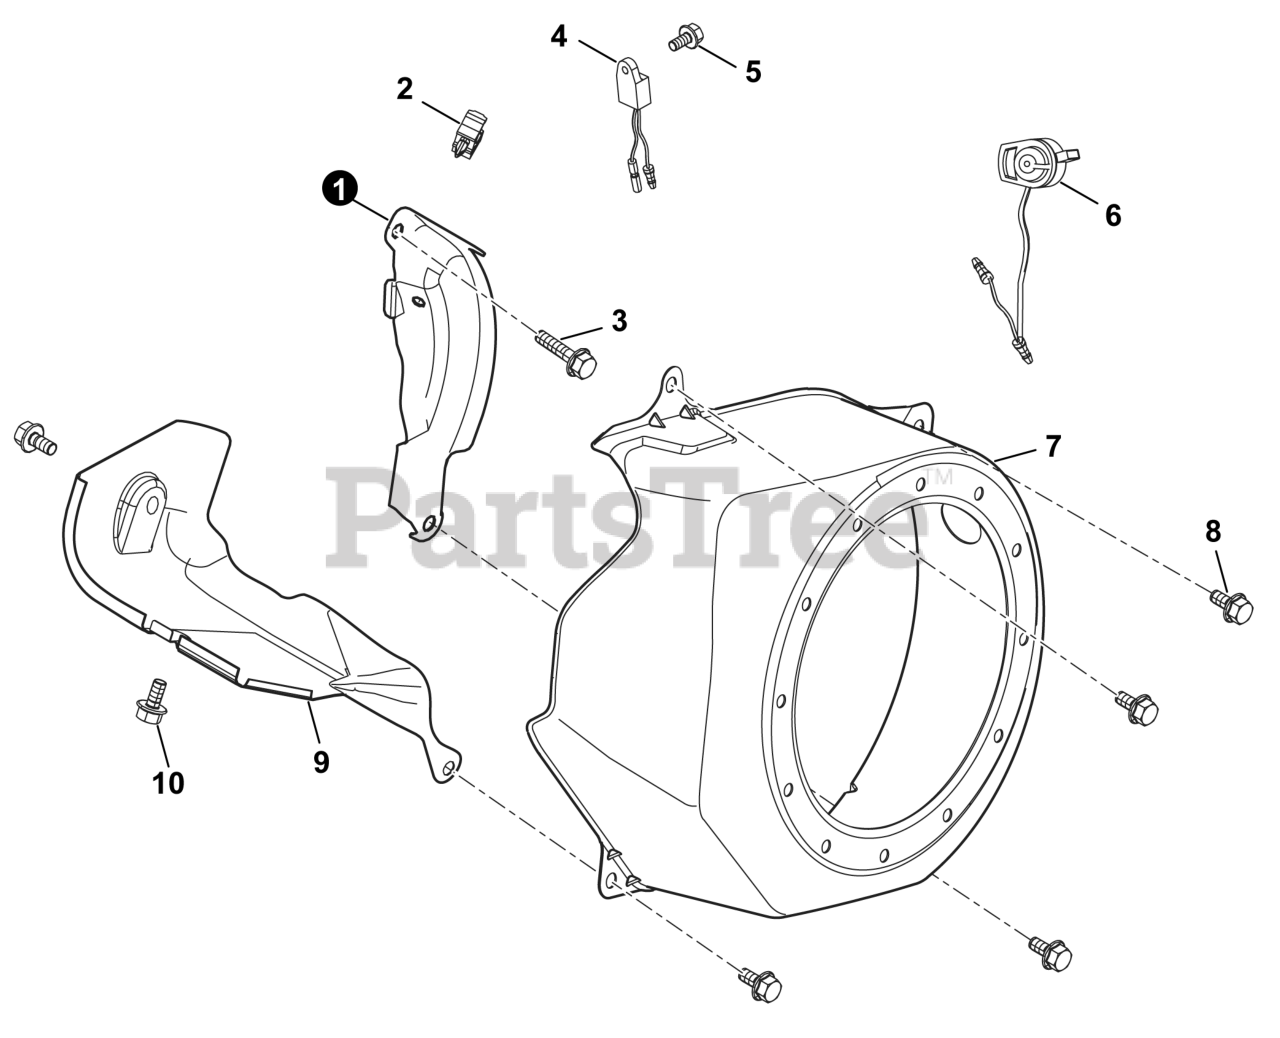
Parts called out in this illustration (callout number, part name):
1	SHIELD,LOWER
4	PROTECTOR, OIL
6	SWITCH, STOP ENGINE
9	SHROUD, CYLINDER BODY
